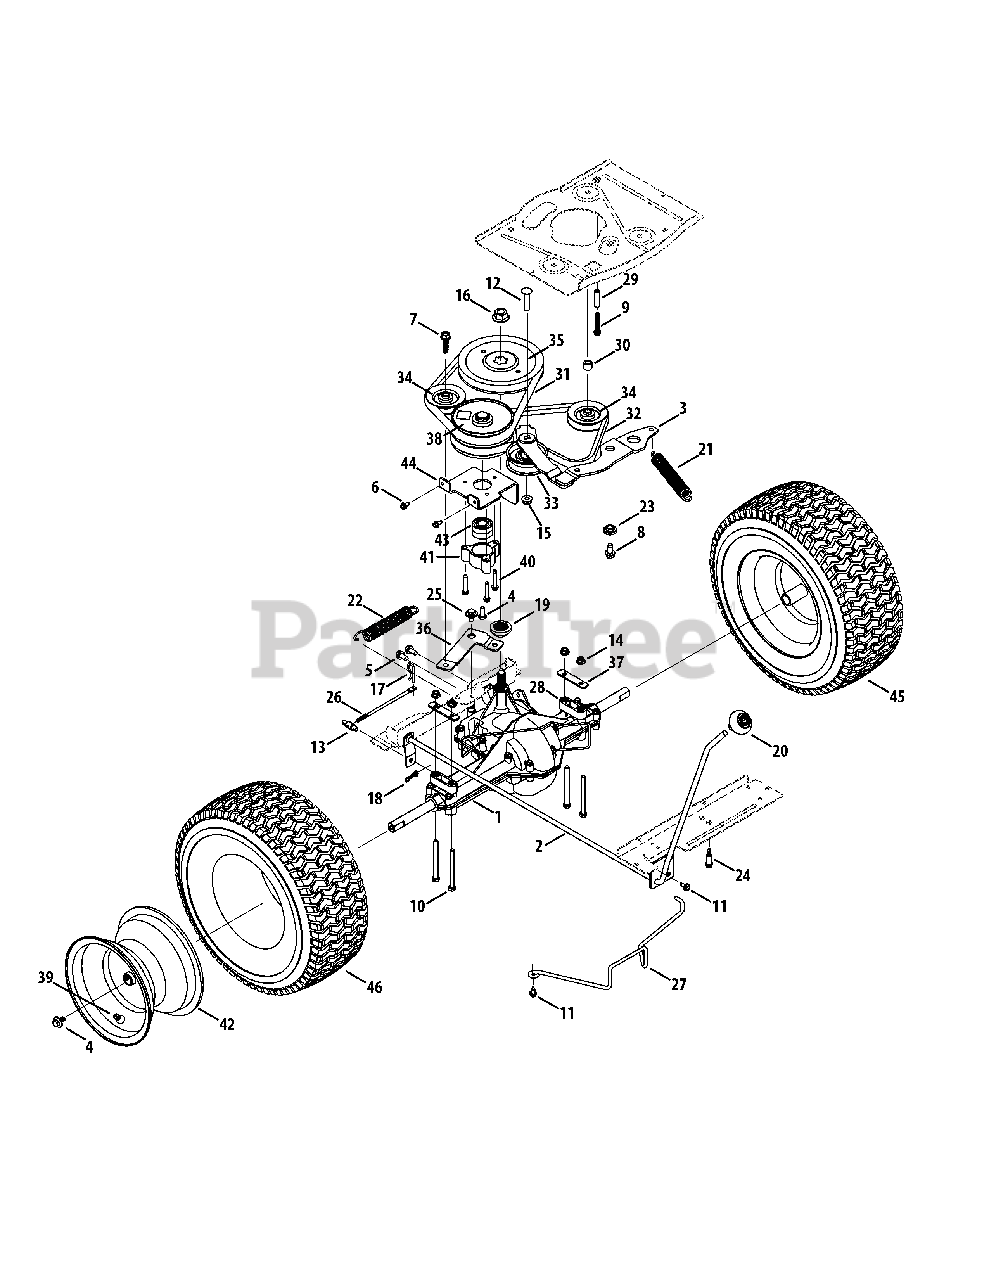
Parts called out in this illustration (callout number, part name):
1	Transmission Assembly
2	Shift Handle Assembly
3	Drive Assembly Idler
4	Screw, 5/16-24 x .750
5	Tap Screw, 5/16-18, .750
6	Tap Scew, 1/4-20, 0.500
7	Screw, 3/8-16 x 1.375
8	Tap Screw, 3/8-16, 0.750
9	Screw, 1/4-20 x 1.750
10	Hex Cap Screw, 5/16-18 x 3.5, Gr5
11	Tap Screw, 1/4-20 x .625
12	Screw, Carriage: 3/8-16 x 1.69"
13	Adjustable Ferrule, 1/4-20 X 1.00
14	Flange Locknut, 5/16-18
15	Flange Lock Nut, 3/8-16
16	Flange Nut, 9/16-18
17	Internal Cotter Pin, .125 Dia.
18	Bow-Tie Cotter Pin
19	Pulley Hub, 5/8 Spline
20	Shift Knob
21	Extension Spring, .94 Dia. X 6.74 Lg.
22	Extension Spring, .97 OD X 6.18
23	Shoulder Spacer, 1.00 X .38 X .38
24	Shoulder Screw, .368 x .75, 1/4-20
25	Shoulder Screw, .560 x .165, 5/16-18
26	Shift Rod
27	Deck Belt Keeper, 30"
28	Spacer
29	Spacer, .260 X .372 X 1.420
30	Spacer, .385 x .625 x .500
31	V-Belt, 5L:35.25
32	V-Belt, 5L:35.28
33	Flat Idler Pulley, 2.75 OD
34	V-Type Idler Pulley, 3.06
35	V-Type Pulley, 6.56
36	Rear Idler Arm Bracket
37	Transaxle Mounting Bracket
38	Variable Speed Pulley Assembly
39	Air Valve
40	Tap Screw, 1/4-20:1.500
41	Bearing Cup
42	Rim Assembly, 8.0 x 5.38
43	Ball Bearing, 17 X 40 X 12
44	Variable Bracket
45	Complete Wheel Assembly
46	Tire, 16 x 6.5 x 8 Sq. Shldr.
